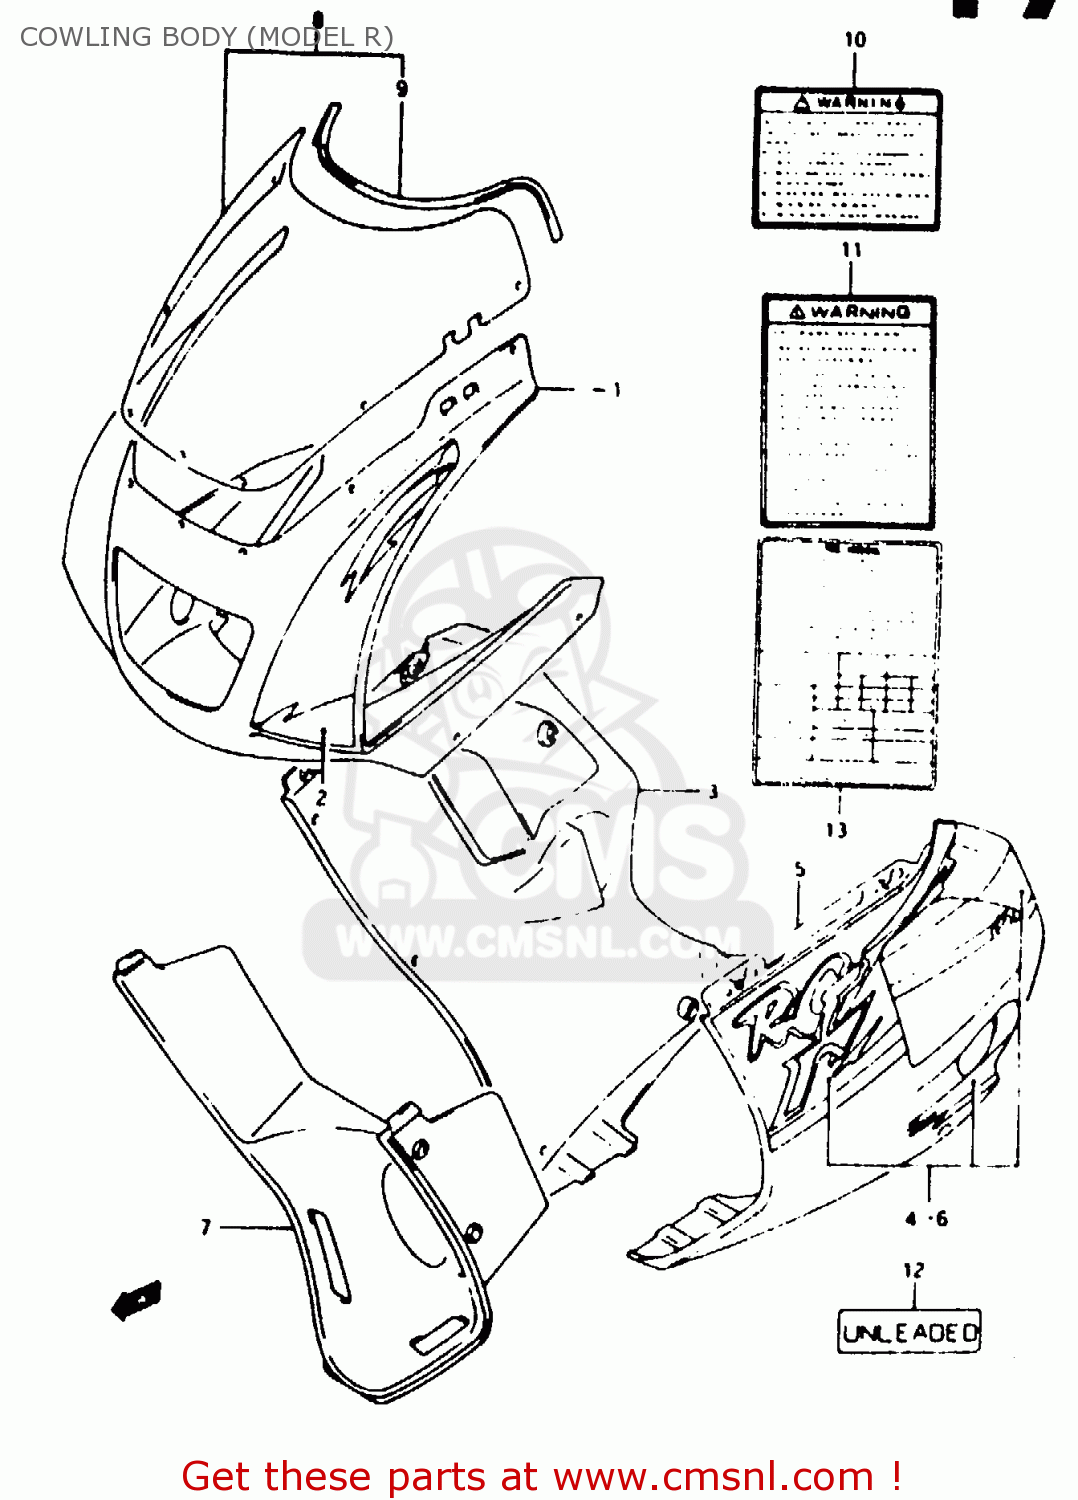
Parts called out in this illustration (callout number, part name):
1	COWLING ASSY, BODY (GRAY)
2	TAPE SET, COWLING
3	COWLING ASSY, UNDER RH (BLUE)
4	TAPE SET, UNDER RH
5	COWLING ASSY, UNDER LH (BLUE)
6	TAPE SET, UNDER LH
7	COWLING, UNDER CENTER (BLACK)
8	SCREEN SET,WIND
9	MOLDING WINDSCREEN
10	LABEL, WARNING SAFETY
11	LABEL (WARNING SCREEN)
12	LABEL,CAUTION
13	LABEL, TIRE AIR PRESSURE
14	MANUAL, OWNER'S
